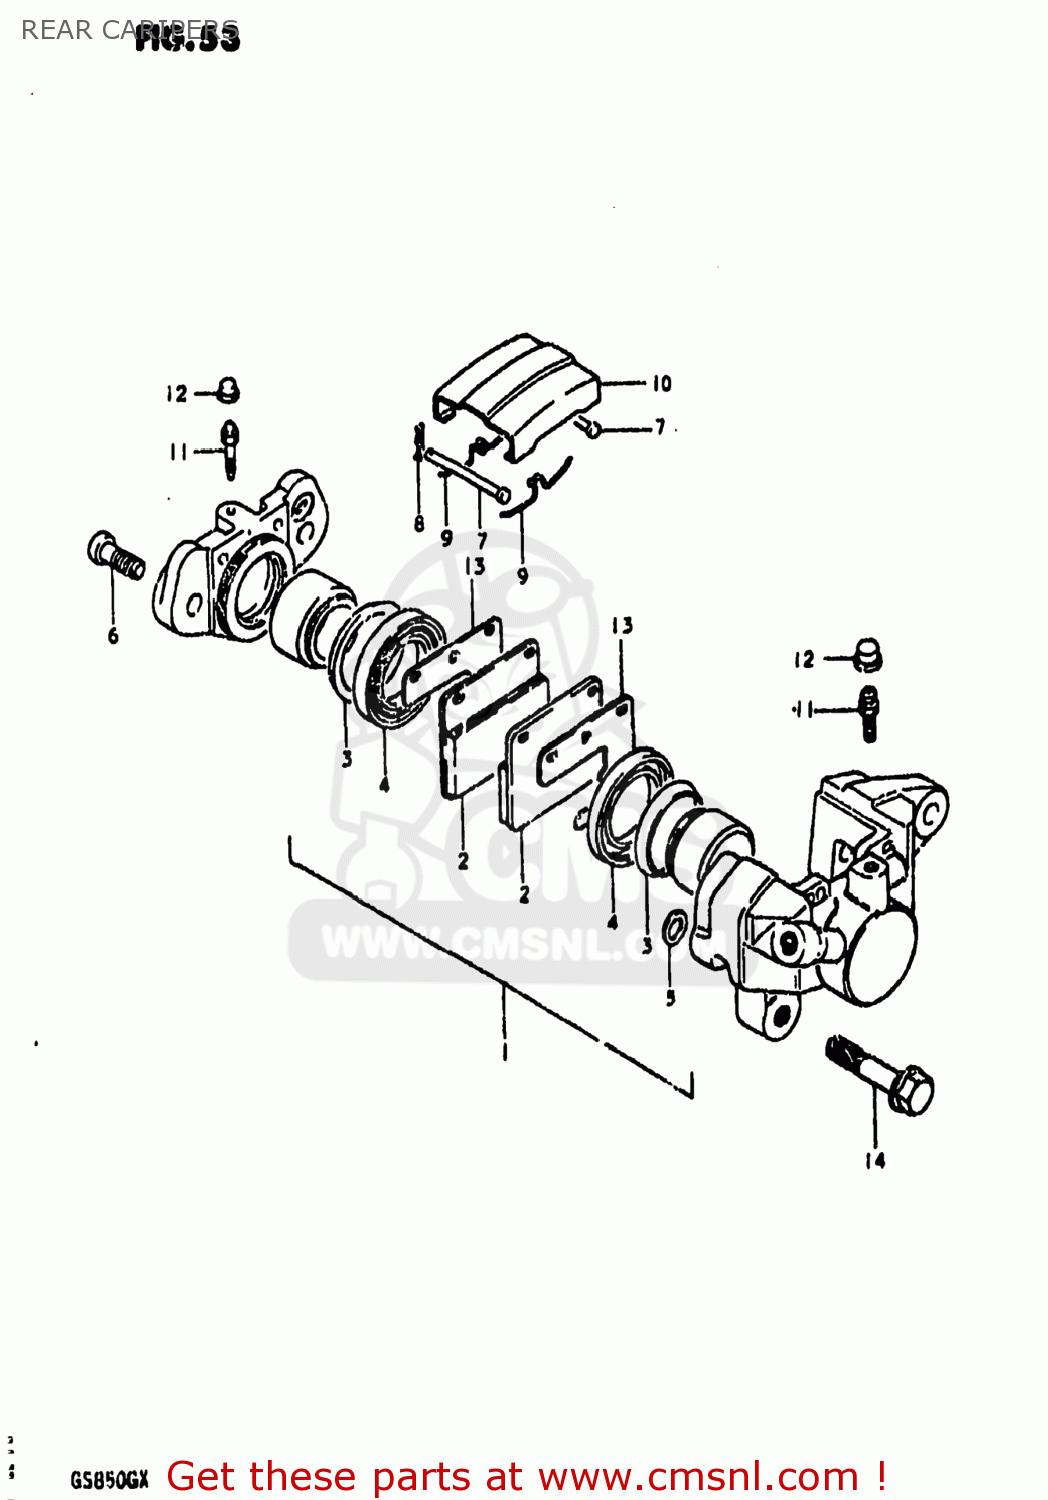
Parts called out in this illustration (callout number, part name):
1	PISTON SET
2	PAD,BRAKE
3	SEAL,PISTON
4	BOOT,PISTON
5	SEAL,PISTON
6	BOLT,HOUSING
7	PIN,PAD
8	CLIP,PAD PIN
9	SPRING
10	COVER,DUST
11	BLEEDER
12	CAP,BREATHER
13	SHIM,RR CALIPER
14	BOLT
